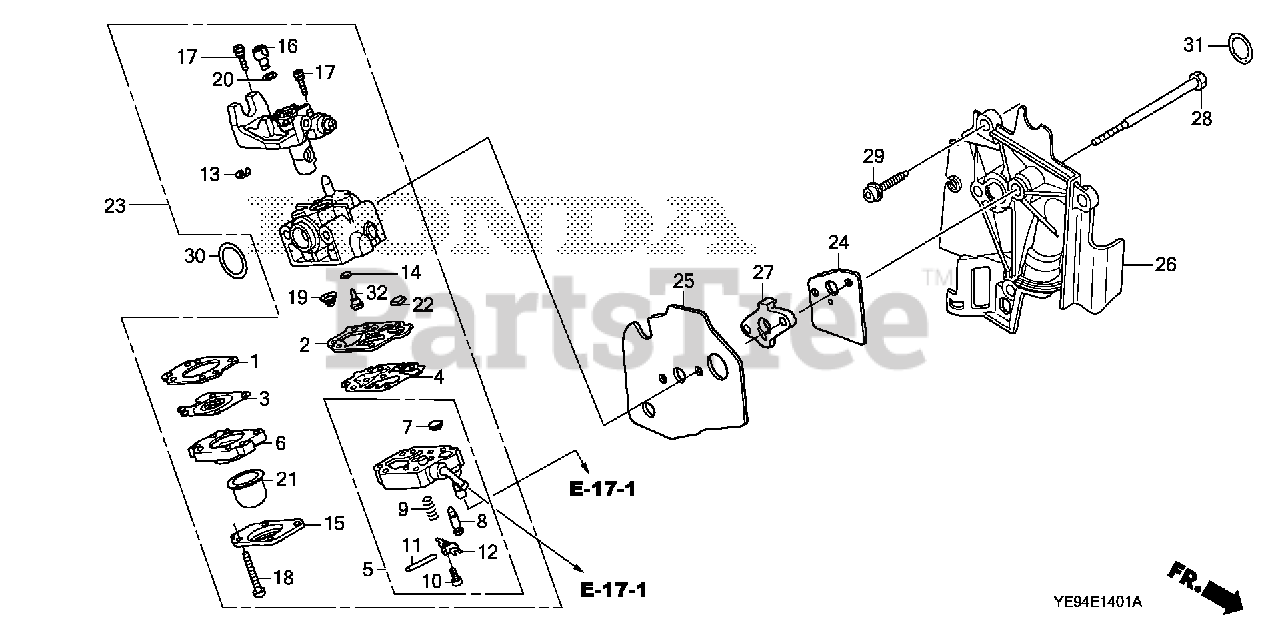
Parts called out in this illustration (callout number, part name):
1	GASKET, METERING DIAPHRAGM
2	GASKET, PUMP (CARBURETOR NO.)
3	DIAPHRAGM ASSY., METERING
4	DIAPHRAGM, PUMP
5	BODY ASSY., PUMP (CARBURETOR NO.)
6	BODY ASSY., AIR PURGE
7	SCREEN, INLET
8	VALVE, INLET NEEDLE
9	SPRING, METERING LEVER
10	SCREW, METERING LEVER PIN
11	PIN, METERING LEVER
12	LEVER, METERING
13	RING, RETAINING
15	COVER, PRIMER PUMP
17	SCREW, THROTTLE COLLAR
18	SCREW, PUMP COVER
19	SPRING, PUMP
21	PUMP, PRIMER
22	FILTER, FUEL INLET
23	CARBURETOR ASSY. (WYB 10B/C)
24	GASKET, CARBURETOR
25	GASKET, SHROUD
27	SPACER, SHROUD
28	BOLT (5X59)
28	BOLT (5X58)
29	BOLT, SOCKET (5X16)
30	O-RING (14.8X2.4)
31	O-RING (12.3X2.4)
32	JET (#33)
32	JET (#32)
